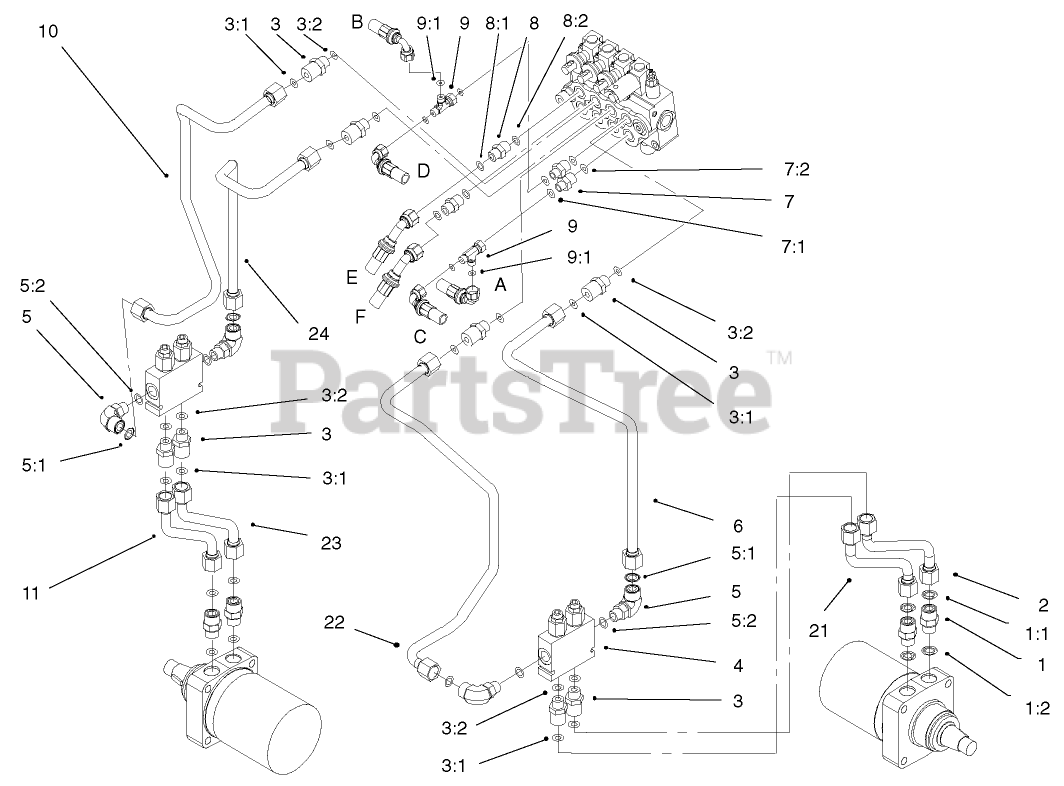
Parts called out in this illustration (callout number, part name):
1	FITTING-STRAIGHT
1:1	O-RING
1:2	O-RING
2	TUBE-HYD
3	FITTING-STR
3:1	O-RING
3:2	O-RING
4	VALVE-COUNTERBALANCE
5	Fitting-Elbow, 90 DEG
5:1	O-RING
5:2	O-RING
6	TUBE-HYD
7	FITTING-STR
7:1	O-Ring
7:2	O-RING
8	FITTING-STRAIGHT
8:1	O-RING
8:2	O-RING
9	FITTING-HYD
9:1	O-RING
10	TUBE-HYD
11	TUBE-HYD
21	TUBE-HYD
22	TUBE-HYD
23	TUBE-HYD
24	TUBE-HYD
